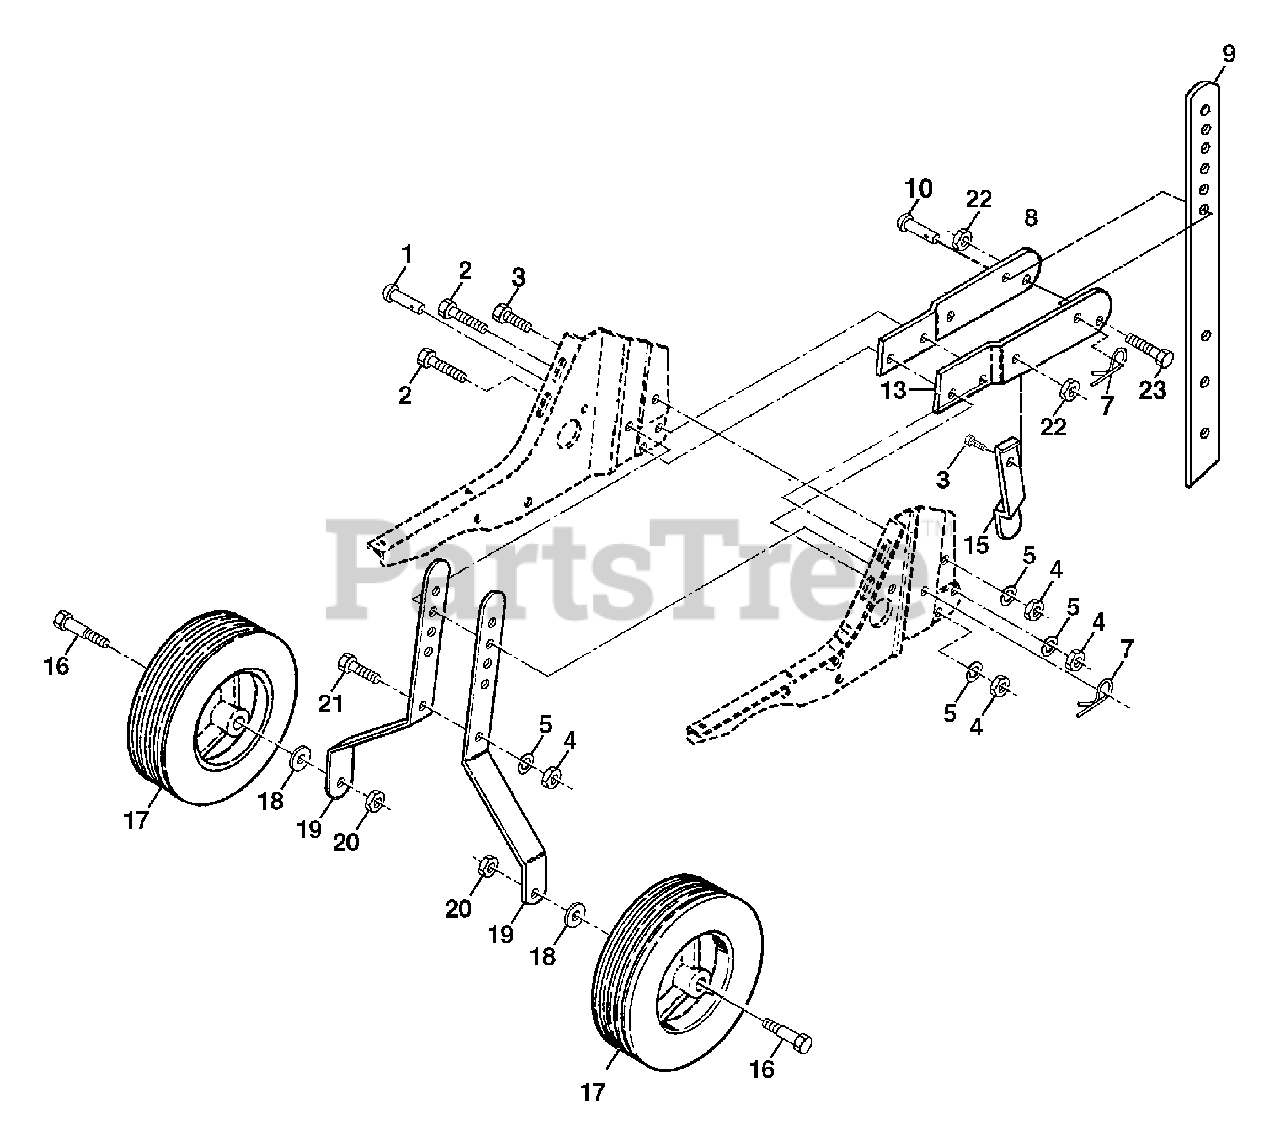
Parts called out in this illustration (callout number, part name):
1	Pin, Clevis
2	Bolt, Hex 5/16-18 x 1-1/4
3	Bolt, Hex 5/16-18 x 3/4
4	Nut, Hex 5/16-18
5	Washer, Lock 5/16
7	Clip, Hairpin
8	Support, Depth Stake, R.H.
9	Stake, Depth
10	Rivet, Drilled
13	Support, Depth Stake, L.H.
15	Spring, Stake
16	Bolt, Shoulder
18	Washer 13/32 x 13/16 x 11 Ga.
19	Bracket, Wheel
20	Locknut, Crown 3/8-16
21	Bolt, Hex 5/16-18 x 1
22	Locknut, w/insert 5/16-18
23	Bolt Fin Hex 5/16-18 UNC x 1-1/2
24	Nut Lock Hex W/Ins 5/16 x 18 UNC
